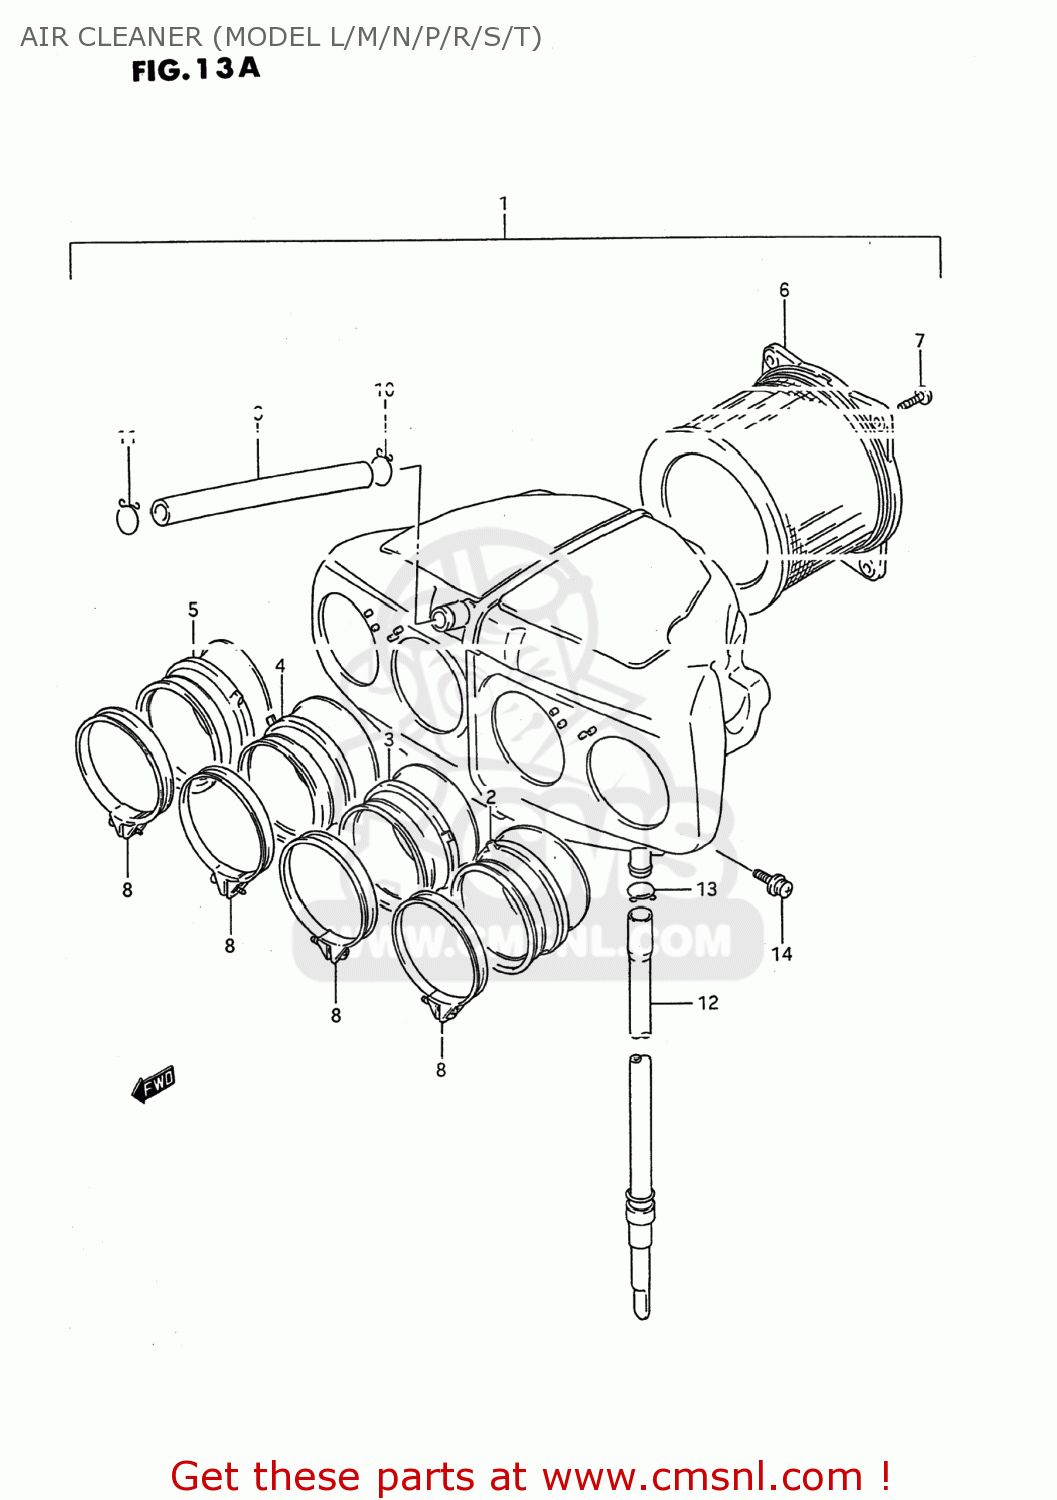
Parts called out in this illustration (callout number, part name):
1	CLEANER ASSY, AIR
2	TUBE,OUTLET,L
3	TUBE,OUTLET ML
4	TUBE,OUTLET MR
5	TUBE,OUTLET,R
6	FILTER ASSY
7	SCREW 5X12
8	CLAMP
9	TUBE,BREATHER
10	CLIP
11	CLIP
12	TUBE,DRAIN
13	CLIP
14	SCREW
